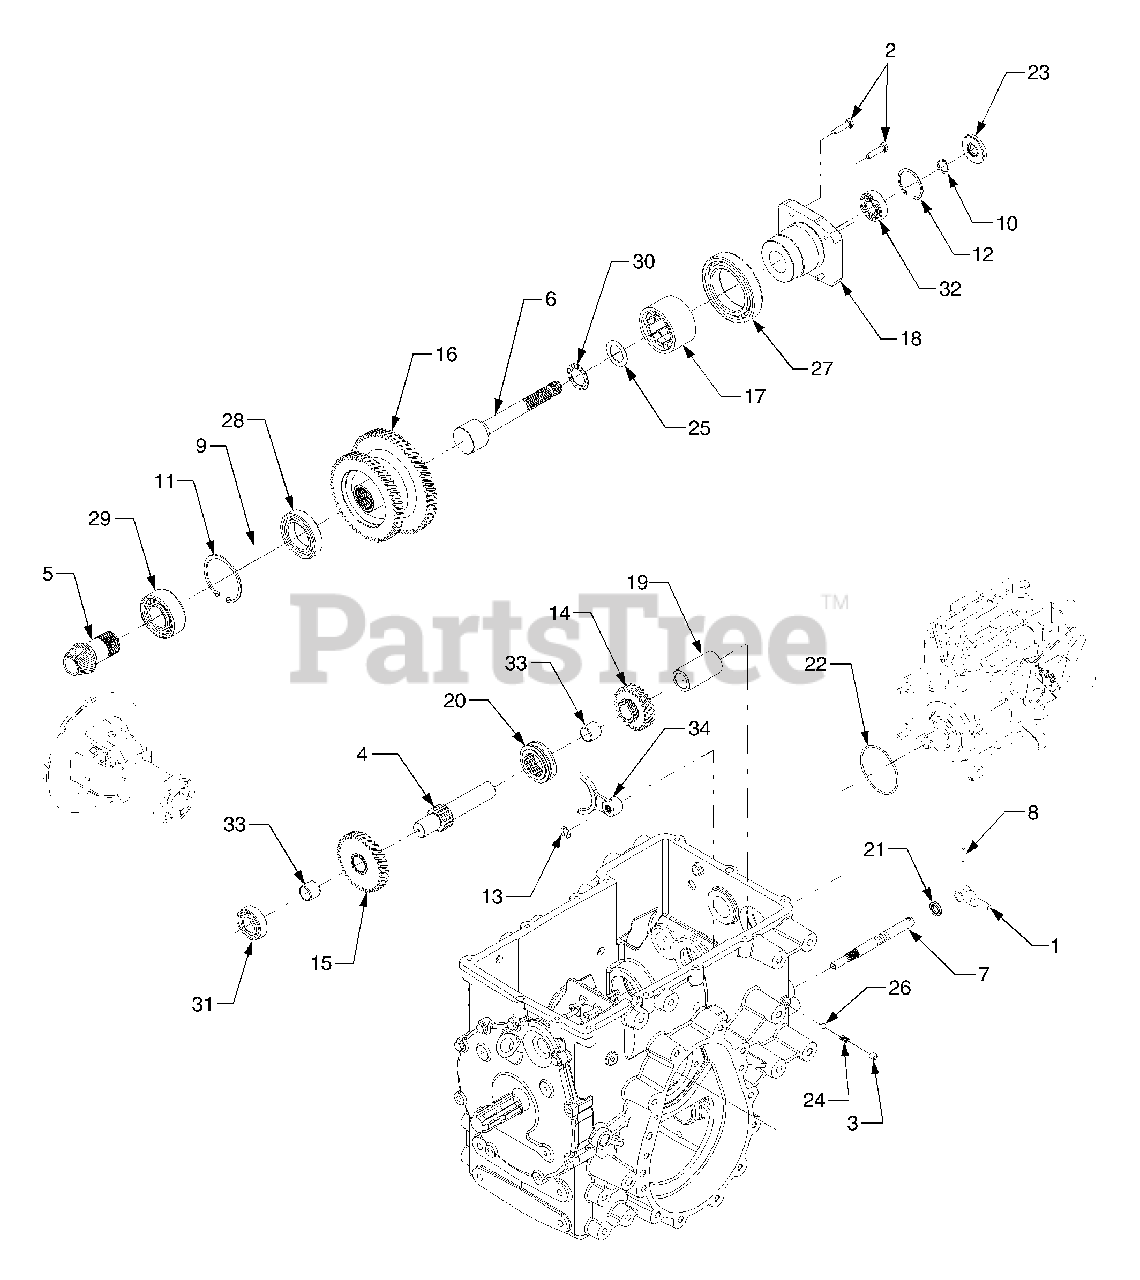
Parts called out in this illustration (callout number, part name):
1	Pin Assembly, 2 Speed
2	Screw, Hex Cap Lock, 5/16-18 x 1.25 GR5
3	Screw, Cup Set, 5/16-18 x 3/8
4	Shaft, Motor
5	Shaft, Pinion, 16T
6	Shaft, 4WD
7	Shaft, 2 Speed Actuator
8	Pin, Spirol, 3/16 x 1.25
9	Ring, E Retaining
10	Ring, Retaining
11	Ring, Retaining
12	Ring, Retaining
13	Clip, Rotor
14	Gear, Drive Pinion, LO 24T:17T
15	Gear, Drive Pinion, HI 33T: 17T
16	Gear, Drive, LO:59T; HI 50T
17	Clutch, Overrunning
18	Cover, Front
19	Spacer, Drive
20	Collar, 2 Speed
21	Seal, Oil
23	Seal, Oil
24	Spring, Detent
25	Washer, Thrust
26	Ball, Detent
27	Bearing, Ball
28	Bearing, Ball
29	Bearing, Angular Contact Ball
30	Bearing, Thrust
31	Bearing, Ball
32	Bearing, Ball
33	Bearing, Sleeve
34	Yoke, 2 Speed
